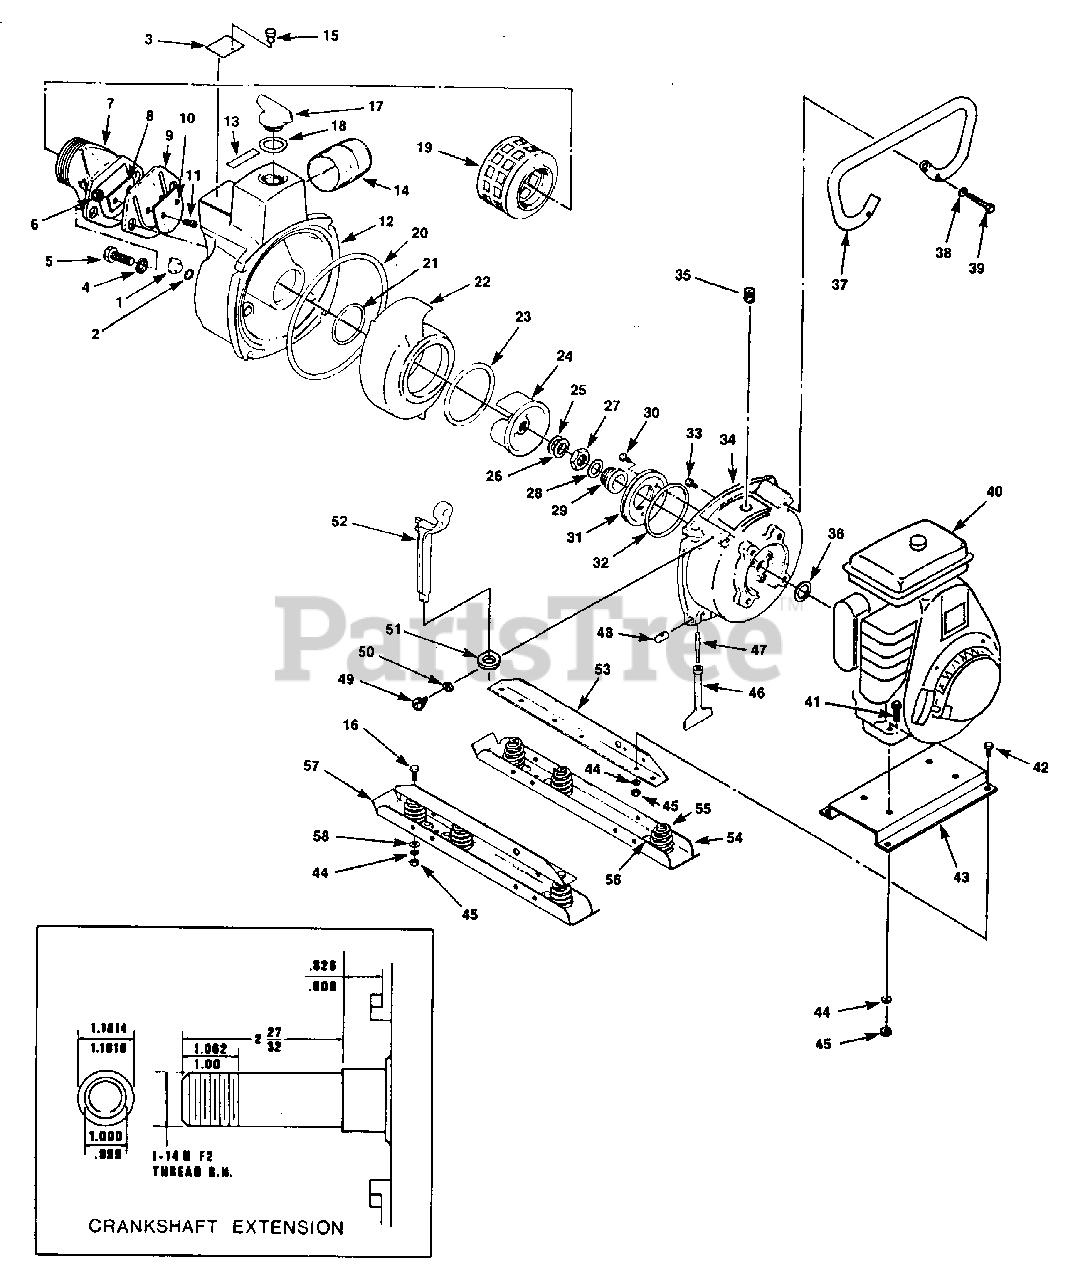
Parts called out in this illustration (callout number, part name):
1	PLUG- Drain
3	DECAL- Plate
4	WASHER- Lock 1/2"
5	SCREW- 1/2-13 x 1 1/4"
6	NUT- Hex 10-32
7	FITTING- Suction std. thread
8	PLATE- Small
10	PLATE- Large
11	SCREW- 10-32 x 1/2"
12	HOUSING- End
15	TACK- Metal
16	SCREW- Hex hd. 5/16-18 x 1"
17	PLUG- Wing
18	GASKET- Wing nut plug
19	STRAINER (1" openings)
20	GASKET- Pump body large
21	GASKET- End plate small
22	HOUSING- Impeller
23	GASKET- Impeller housing
24	IMPELLER
25	SHIM (.032") impeller
26	SHIM (.015") impeller
27	NUT- Impeller
28	SHIM- (.010") seal spring pressure
29	SEAL ASSEMBLY- Pump
30	SCREW- Hex hd. 1/4-20 x 5/8"
31	PLATE- Wear
32	"O" RING
33	SCREW- Hex hd 3/8-16 x 1 1/4"
34	BODY- Pump
36	SLINGER
37	HANDLE- Carrying
38	WASHER- Flat 3/8"
39	SCREW- Hex hd. 3/8-16 x 1 3/4"
41	SCREW- Hex hd. 5/16-18 x 1 3/4"
42	SCREW- Hex hd. 5/16-18 x 3/4"
43	BRACKET- Pump engine
44	WASHER
45	NUT- Hex 5/16-18
46	HANDLE- Disconnect
47	STUD- Handle
48	PIVOT- Handle
49	SCREW- Hex hd. 1/4-20 X 3/8"
50	WASHER- Flat 1.4"
51	BRACKET- Spanner wrench
52	WRENCH- Spanner
53	ANGLE- Base (right)
55	SPRING- Foot
57	ANGLE- Base (left)
58	WASHER- Flat 5/16
